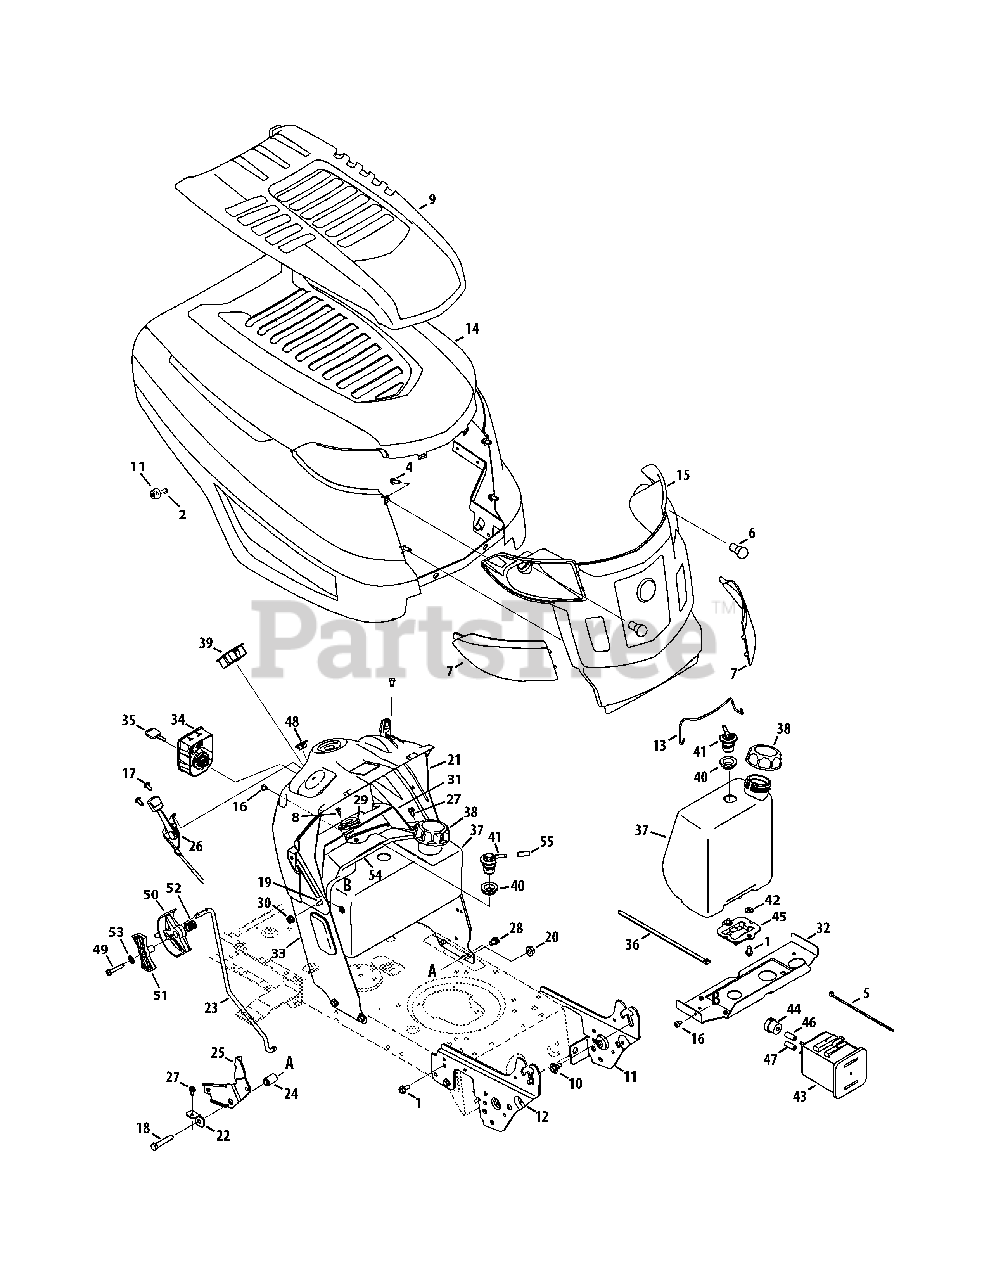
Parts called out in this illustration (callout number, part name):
1	Screw 5/16-18 x .750
2	Screw, #12-16 x 1.25
3	K-Style Bumper
4	Screw, 1/4 x .750
5	Cable Tie
6	Miniature lamp 12V socket
7	Grill Lens - LH
7	Grill Lens - RH
8	Screw, #10-16 x .500
9	Hood Scoop
10	Shoulder Screw .43 x .29
11	Suppport Bracket LH
12	Suppport Bracket RH
14	Hood
16	Screw, 1/4-20 x .500
17	Screw 1/4-20 x .500
18	Hex Screw 3/8-16 x 2.00
19	Hex Screw, 5/16-18 x .625
20	Flange Lock Nut 3/8-16
21	Dash, Upper
22	Speed Latch Tab
23	Speed Control Rod
24	Flange Spacer .39 x .671 x 1.095
25	Transmission Speed Latch
26	Throttle/Choke Control Cable
27	Hex Screw Washer 1/4-20 x .500
28	Screw 5/16-18 x .625
29	Bearing, .628 ID x 1.36
30	Flange lock Nut 5/16-18
31	Bracket, Steering Support
32	Gas Tank Support Bracket
33	Dash, Lower
34	Key Switch Module
36	Cable Tie
37	Fuel Tank, 2 Gallons, EPA
37	Fuel Tank, 1.36 Gallon, CARB
38	Fuel Cap
38	Fuel Cap, CARB
39	Ammeter Monitor Indicator
40	Rubber Grommet
41	Rollover Valve
42	Washer, Flat, .344 x .750 x .120
43	Canister, Carbon, 5 Gallon
44	Filter, Vent, Canister
45	Bracket., Adapter, Canister
46	Hose, Fuel, Low Perm., White
47	Hose, Fuel, Low Perm., Yellow
48	Choke Plug
49	Hex Washer Screw, 1/4-20 x 1.50
50	Shift Lever
51	Index Control
52	Compr. Spring, .72 OD x .78
53	Lock Washer, 1/4
54	Fuel Tank Clamp Rod
55	Hose Vent, 3/16 EPA
